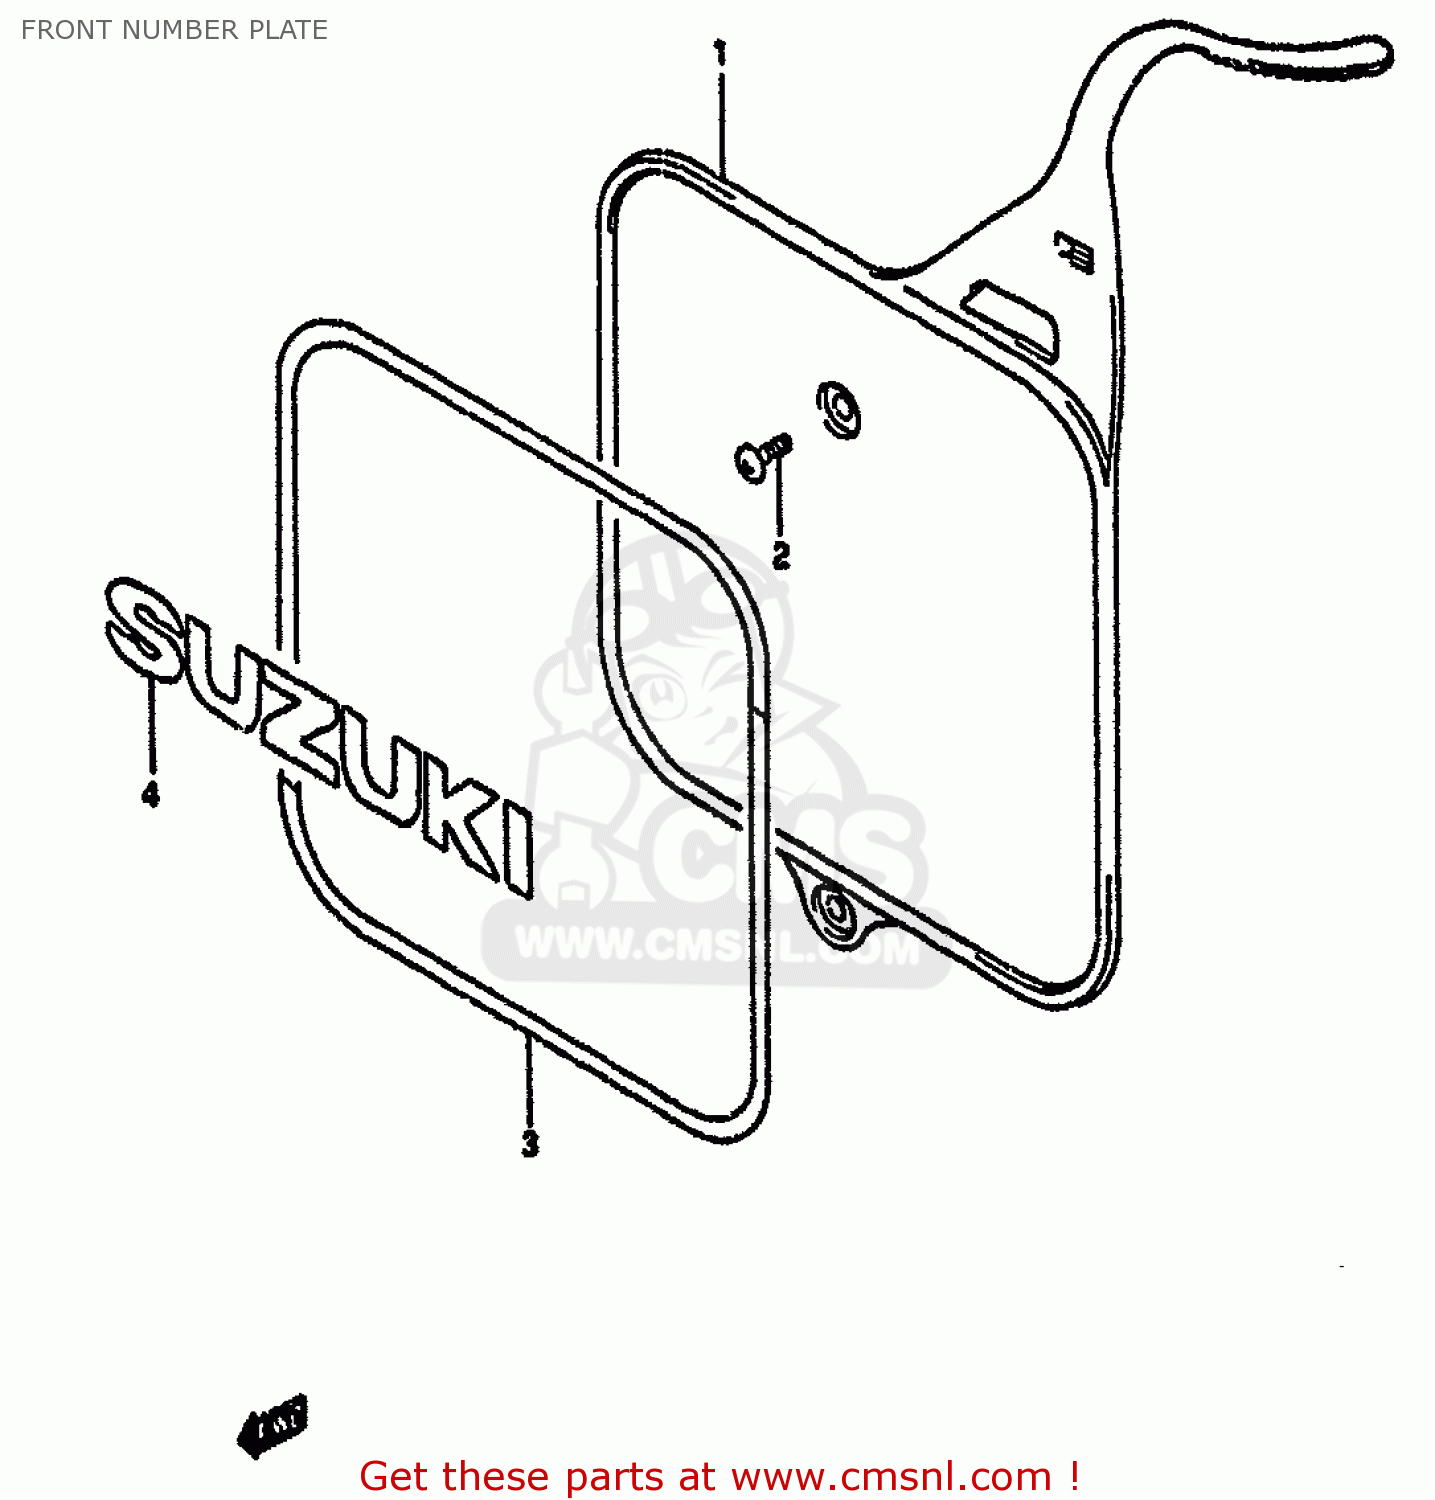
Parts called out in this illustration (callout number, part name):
1	PLATE,NUMBER,FRONT
2	SCREW
3	TAPE SET,FRONT NUMBER
4	EMBLEM,SUZUKI
